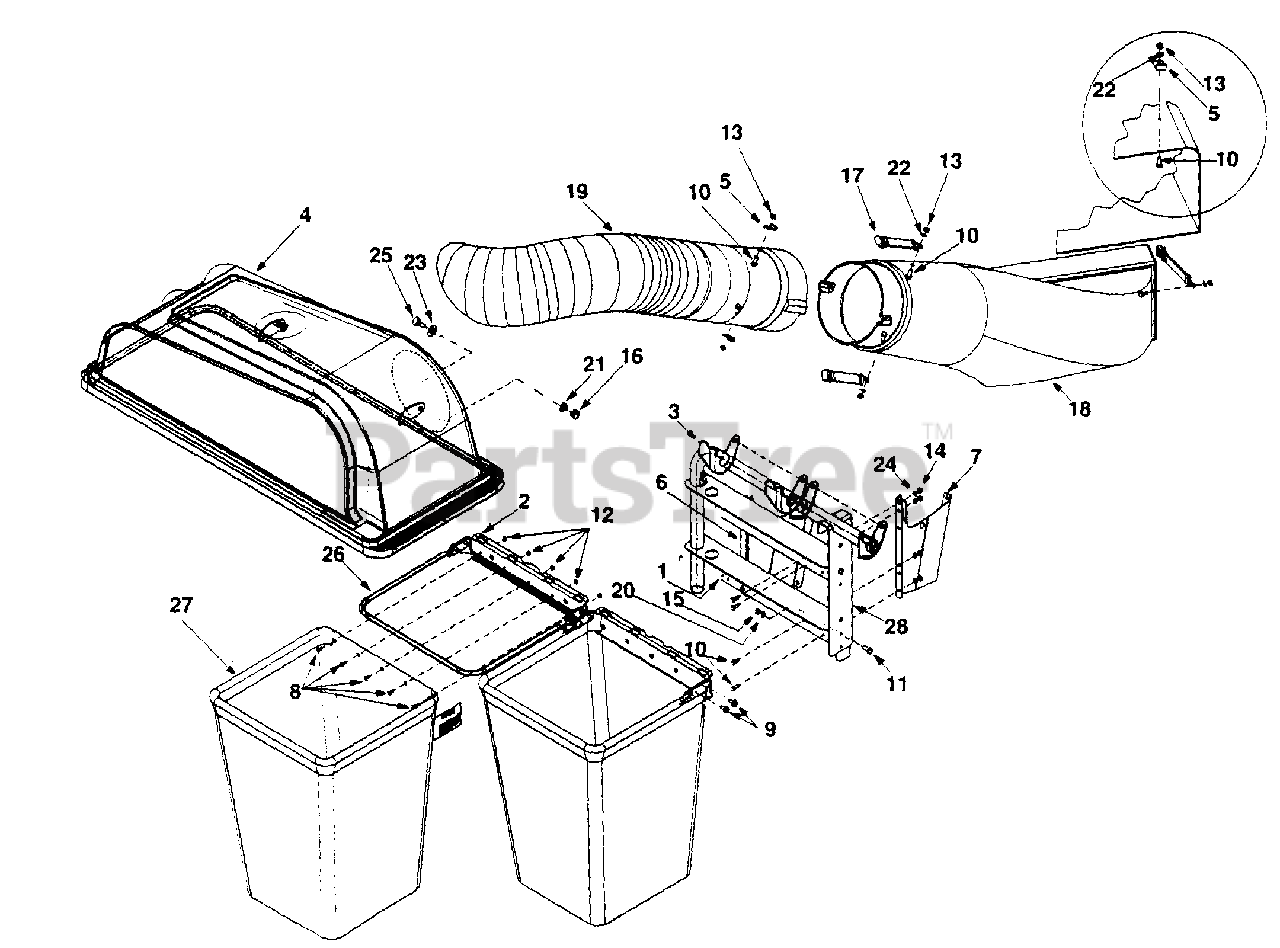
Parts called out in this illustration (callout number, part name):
4	Cover Assembly
5	Retainer Hook Bracket
6	Support Bracket: LH
8	Mach. Screw: #10-24 X 0.5"
9	Screw, TT:5/16-18 X 0.625"
10	Hex Bolt: 1/4-20 X 0.620" Gr. 5
11	Hex Bolt: 511 6-18 X 0.75" Gr. 5
12	Hex Sems Nut: 10-24
13	Hex Lock Nut
14	Hex Nut: Gr. 5
15	Hex Nut: 5/16-18
16	Hex Nut: 3/8-16 Gr. 8
17	Retainer Strap Assembly
18	Discharge Chute
19	Chute Tube
20	Lock Washer: 5/16
21	Lock Washer
22	Spring Washer
23	Bell Washer
24	Lock Washer: 1/4
25	Shoulder Screw
27	Catcher Bag
